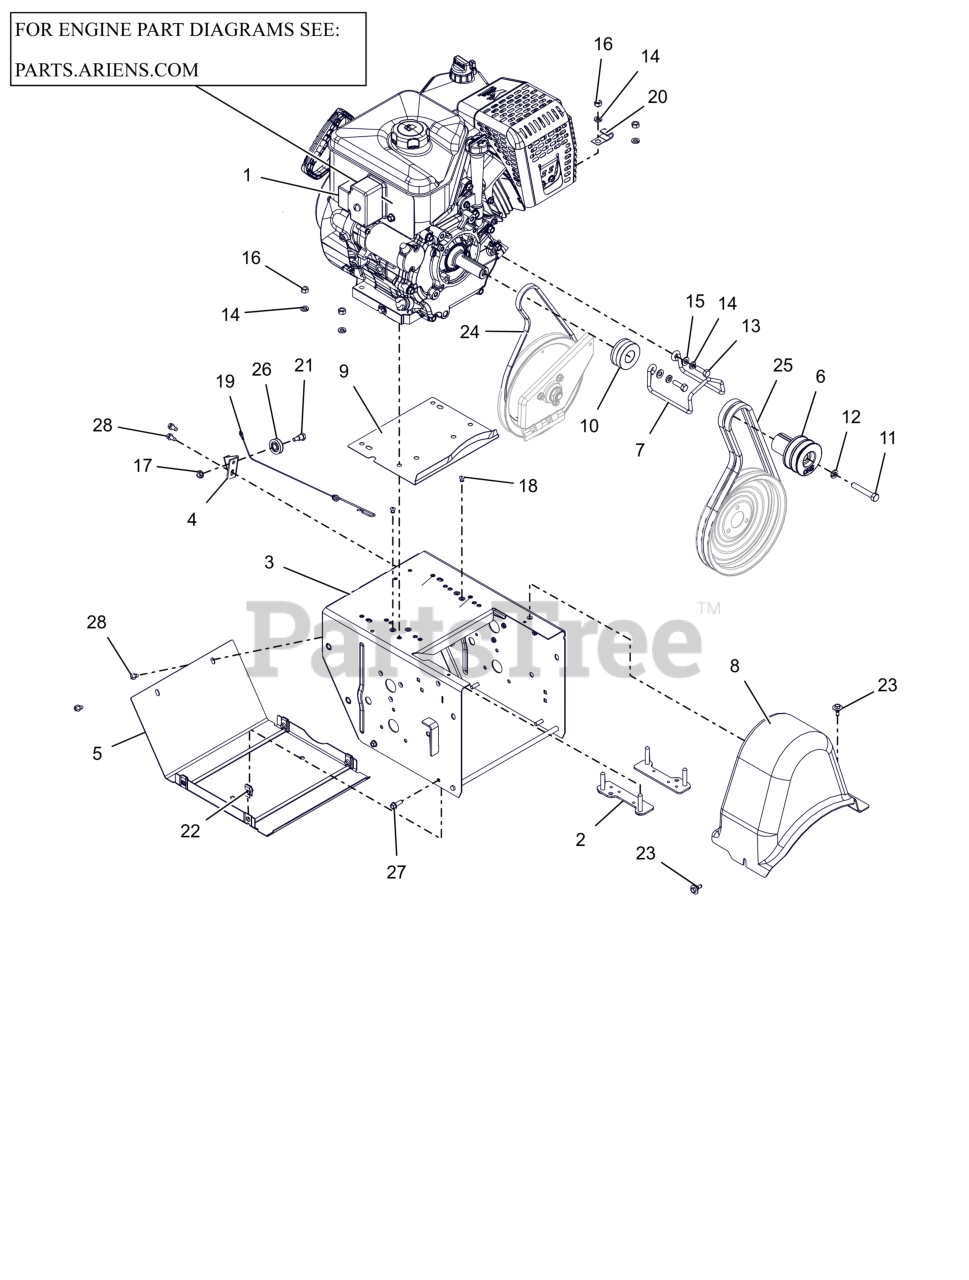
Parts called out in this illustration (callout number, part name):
1	ENGINE, AX369 GEN3 120V/60W
2	STRAP, BOLT-LARGE
3	FRAME, MAIN - 14GA DELUXE (ORANGE)
4	BRACKET, CABLE PULLEY
5	COVER, BOTTOM
6	SHEAVE,ATTACHMENT-SHO 2 GRV
7	FINGER, BELT
8	COVER, BELT-LARGE
9	BAFFLE, WATER - LARGE BLOCK
10	SHEAVE, TRACTION (KEYLESS)
11	BLT, HEX .38-24X2.25 G5 ZCC
12	WSHR,LK-REG .375X.094 ZCC
13	BLT, HEX 0.3125-24X1 G5 ZCC
14	WSHR, LK-HVY .312X.097 ZCC
15	WSHR,FLT .344X.688X.065 ZCC
16	NUT, HEX .312-18 ZCC
17	NUT-LK-TOP-FLG .250-20 GF ZCC
18	RVT, POP .1875 ZCC
19	CABLE, LOWER TRACTION,SS & PRO
20	J-CLAMP
21	BOLT, SHLDR -.375 X .375 X .25-20
22	NUT-RTNR .25-20X.56
23	SCR-TAP .25-20X.5 CAPTIVE
24	V-BELT, 3L-WRAPPED
25	V-BELT, HA-RAW EDGE (SET)
26	PULLEY, CABLE
27	BLT, HWH .25-20X.75 G5 ZCC
28	SCR-TAP .25-20X.50 HWH ZCC
